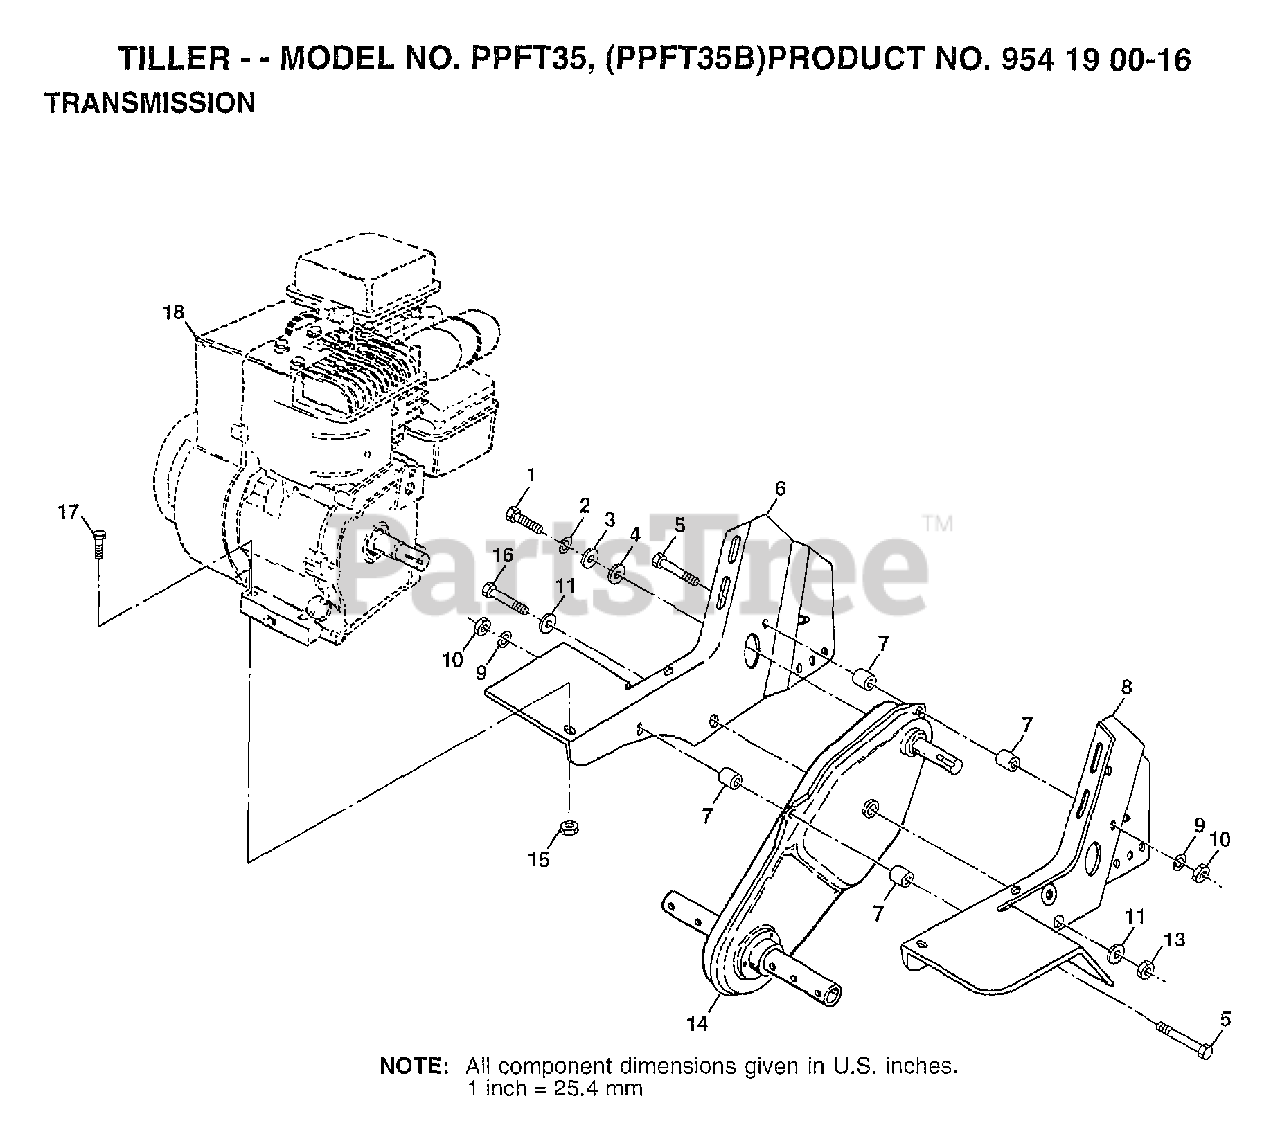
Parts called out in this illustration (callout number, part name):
1	BOLT
2	LOCKWASHER
3	WASHER
4	WASHER
6	ENGINE BRKT RH
7	SPLIT SPACER RT
8	ENGINE BRKT LH
9	LOCKWASHER
10	NUT.HEX.5/16-18
11	WASHER
13	NUT
16	BOLT HEX 3/8-16
17	BOLT.HEX.5/16-1.5
